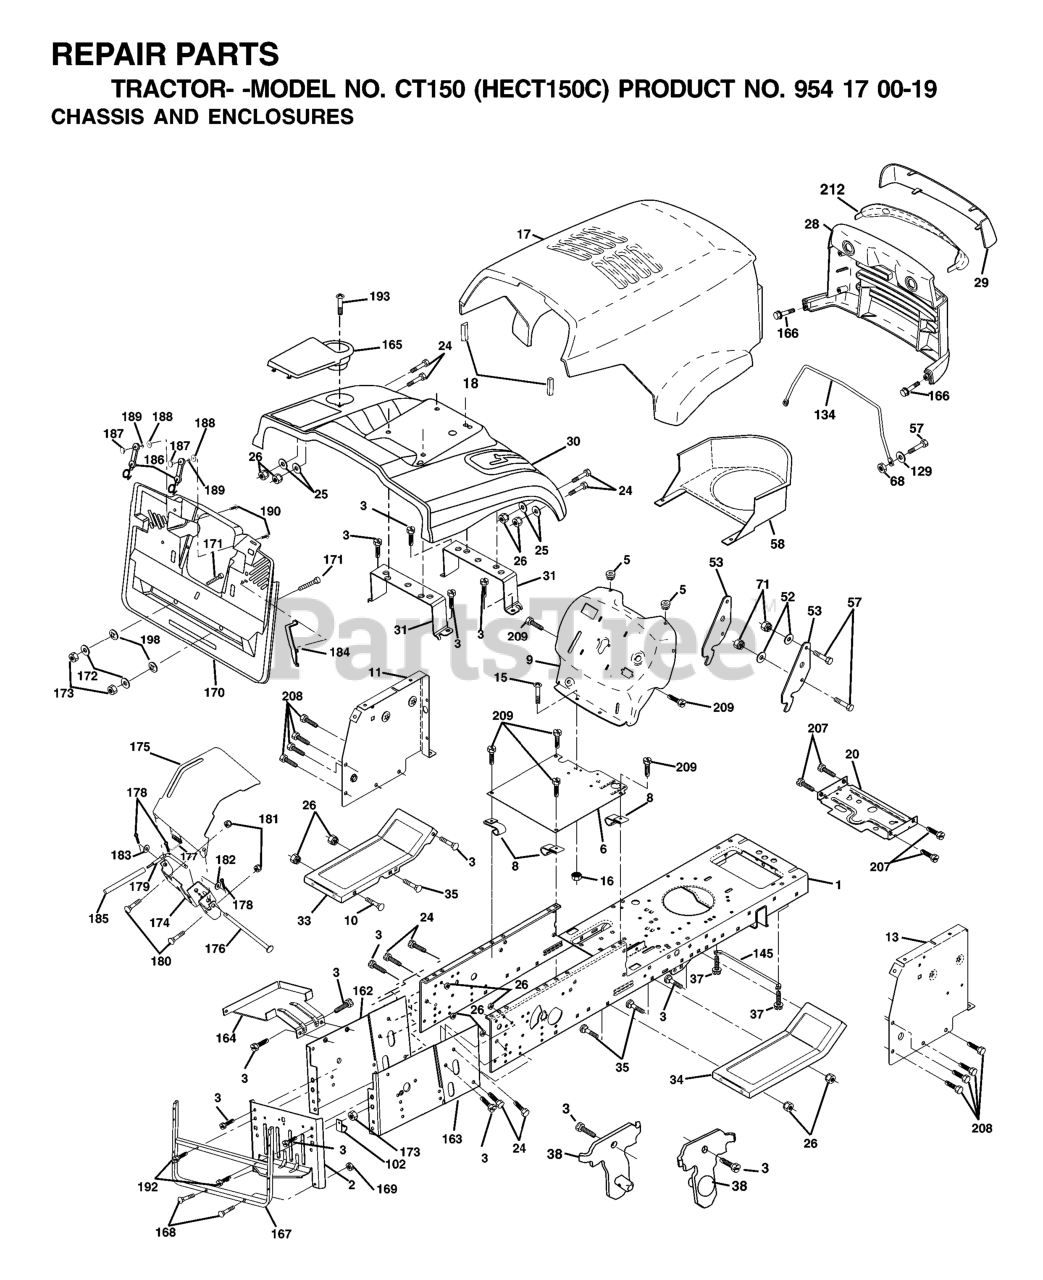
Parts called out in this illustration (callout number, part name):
1	CHASSIS STAMPING
3	SCREW 3/8-16X3/4
5	BUMPER.RUBBER.HOOD
6	SADDLE FLAT
8	CLIP,INSULATOR
10	BOLT D
11	PANEL DASH LH
13	DASH PANEL RH
15	Screw, Machine, Truss Head 5/16-18 UNC x 3/4
16	NUT
17	HOOD
18	BUMPER HOOD T
20	PLATE MTG
25	WASHER
26	NUT
28	GRILL
29	LENS
31	BRACKET SUPPORT FENDER
33	FOOT REST LH
34	FOOTREST RH
37	Screw 5/16-18 x 1/2 Hex, Self Tapping 5/16-18 x 1/2
38	BRACKET
53	BRACKET PNT PICK OFF LT/PL
57	BOLT
58	AIR DUCT P/L/LT
68	NUT
71	NUT.CROWNLOCK.1/4
102	CLIP T
134	ROD SUPPORT HOOD LT/PL HUS.
145	ROD PIVOT CHASSIS/HOOD
162	Bracket Exten Chassis Lh CRD
165	COVER BATTERY
166	SCREW
167	SUPPORT.ASM.BACKPLATE
168	BOLT.ROUND.HEAD.SQUARE.NECK
169	NUT T
170	BACKPLATE ASM
171	Bolt Hex 3/8-16 x 2-1/2 Gr. 5
172	WASHER
176	HINGE PIN
177	SPRING COVER LH
178	COTTER PIN
180	BOLT RB
181	LOCKNUT
183	WASHER
184	BRACKET.ACTUATOR.BAGGER.SRD
185	TUBE LEVER
186	LATCH ASSY
187	WELDNUT
189	LOCKWASHER #10
190	SCREW
192	SCREW 3/8-16 X 1-1/2
193	Screw Truss 1/4-20 x 3/4 Tap/R
207	SCREW, 5/16-18 X 1/2
208	SCREW 3/8-16X1/2
209	SCREW, 3/8-16X3/4
212	INSERT LENS REFLECTOR
